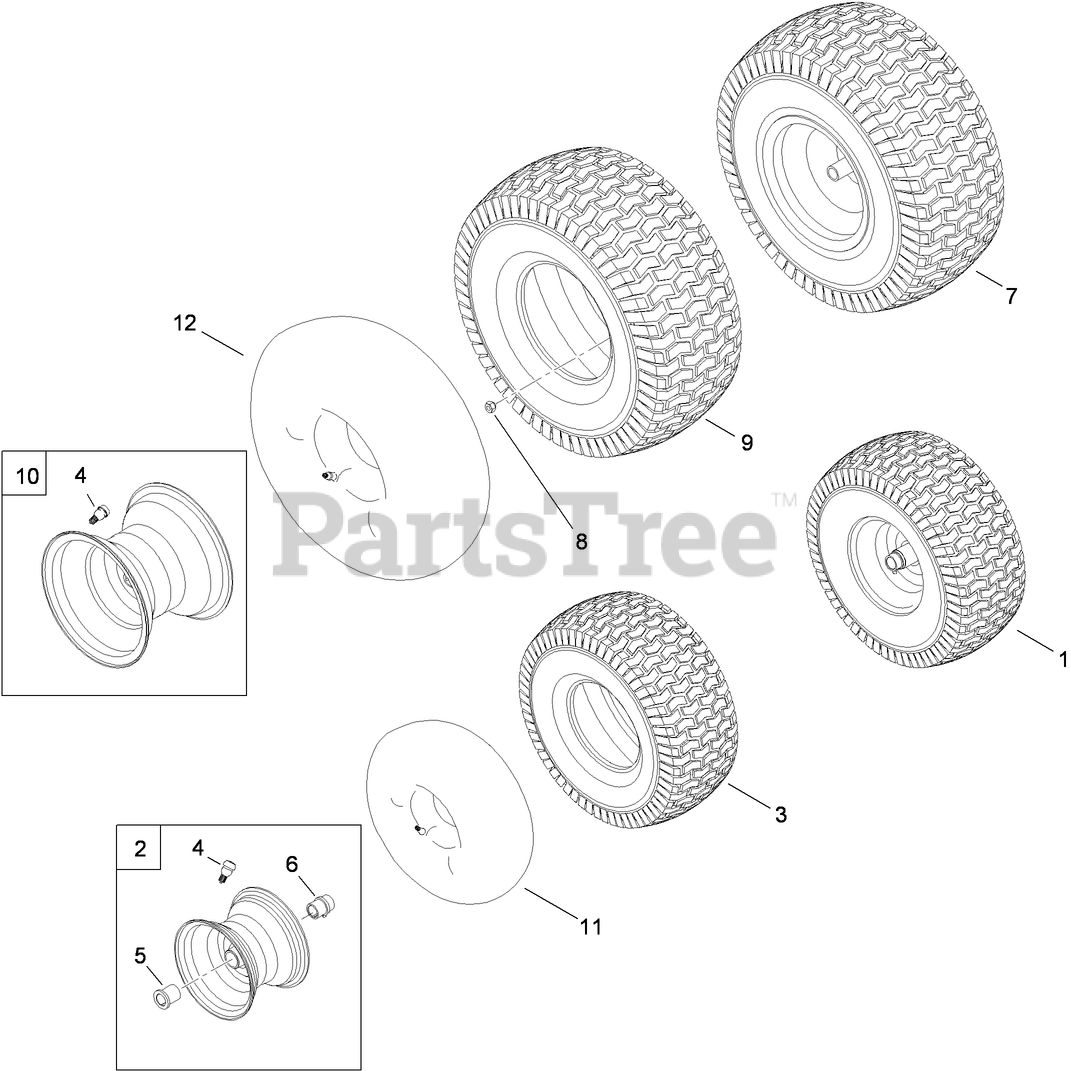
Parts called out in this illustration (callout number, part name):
1	TIRE AND WHEEL ASM
2	RIM ASM
4	VALVE-AIR, TUBELESS
5	BEARING-FLANGE
6	BEARING-FLANGE (W/ZERK)
7	WHEEL ASM
8	NUT-LUG
9	TIRE-TURF
10	RIM ASM
11	TUBE-INNER
